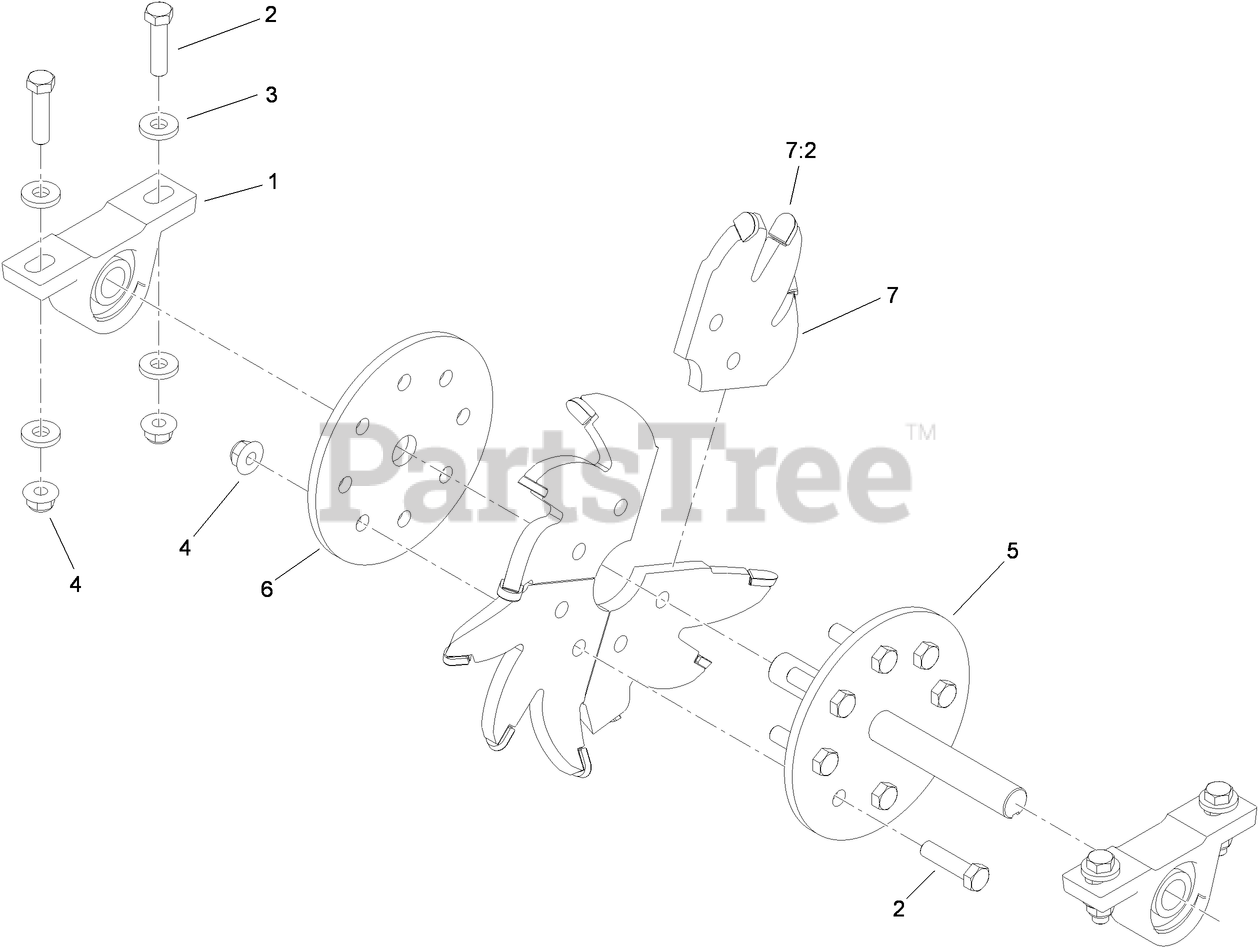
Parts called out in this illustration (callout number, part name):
1	BEARING
2	SCREW-HH
3	SPACER
4	NUT-HF, NI
5	BLADE SHAFT ASM
6	PLATE-FLANGE, SHAFT
7	Blade-Grinder
7:2	TIP-CARBIDE
